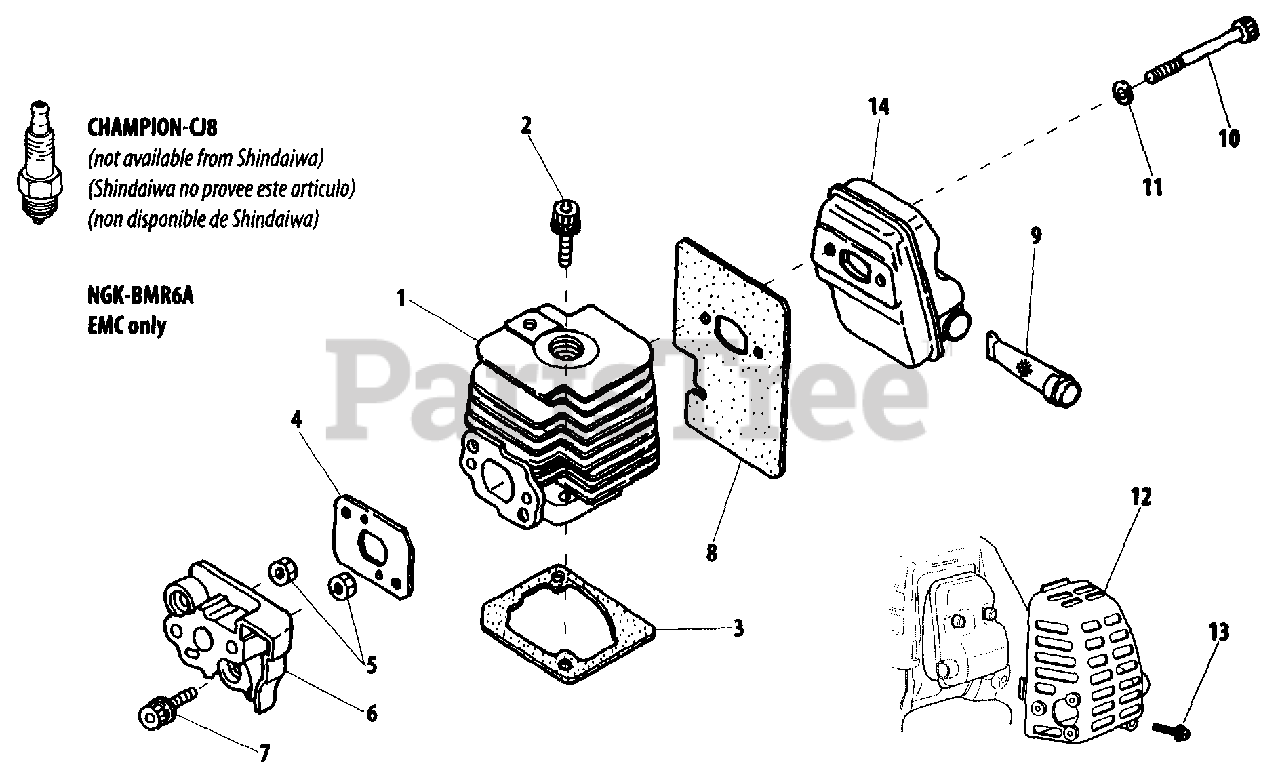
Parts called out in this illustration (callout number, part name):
1	CYLINDER
2	BOLT M5×25
3	GASKET, CYLINDER
4	GASKET
5	NUT M5×6.3
6	INSULATOR, INTAKE
7	BOLT M5×25
8	HEAT SHIELD, EXHAUST
9	SCREEN, SPARK ARRESTER
10	BOLT 5×40
11	WASHER, FLAT 5.5×10×0.8
12	COVER, MUFFLER
13	SCREW M5
14	MUFFLER
